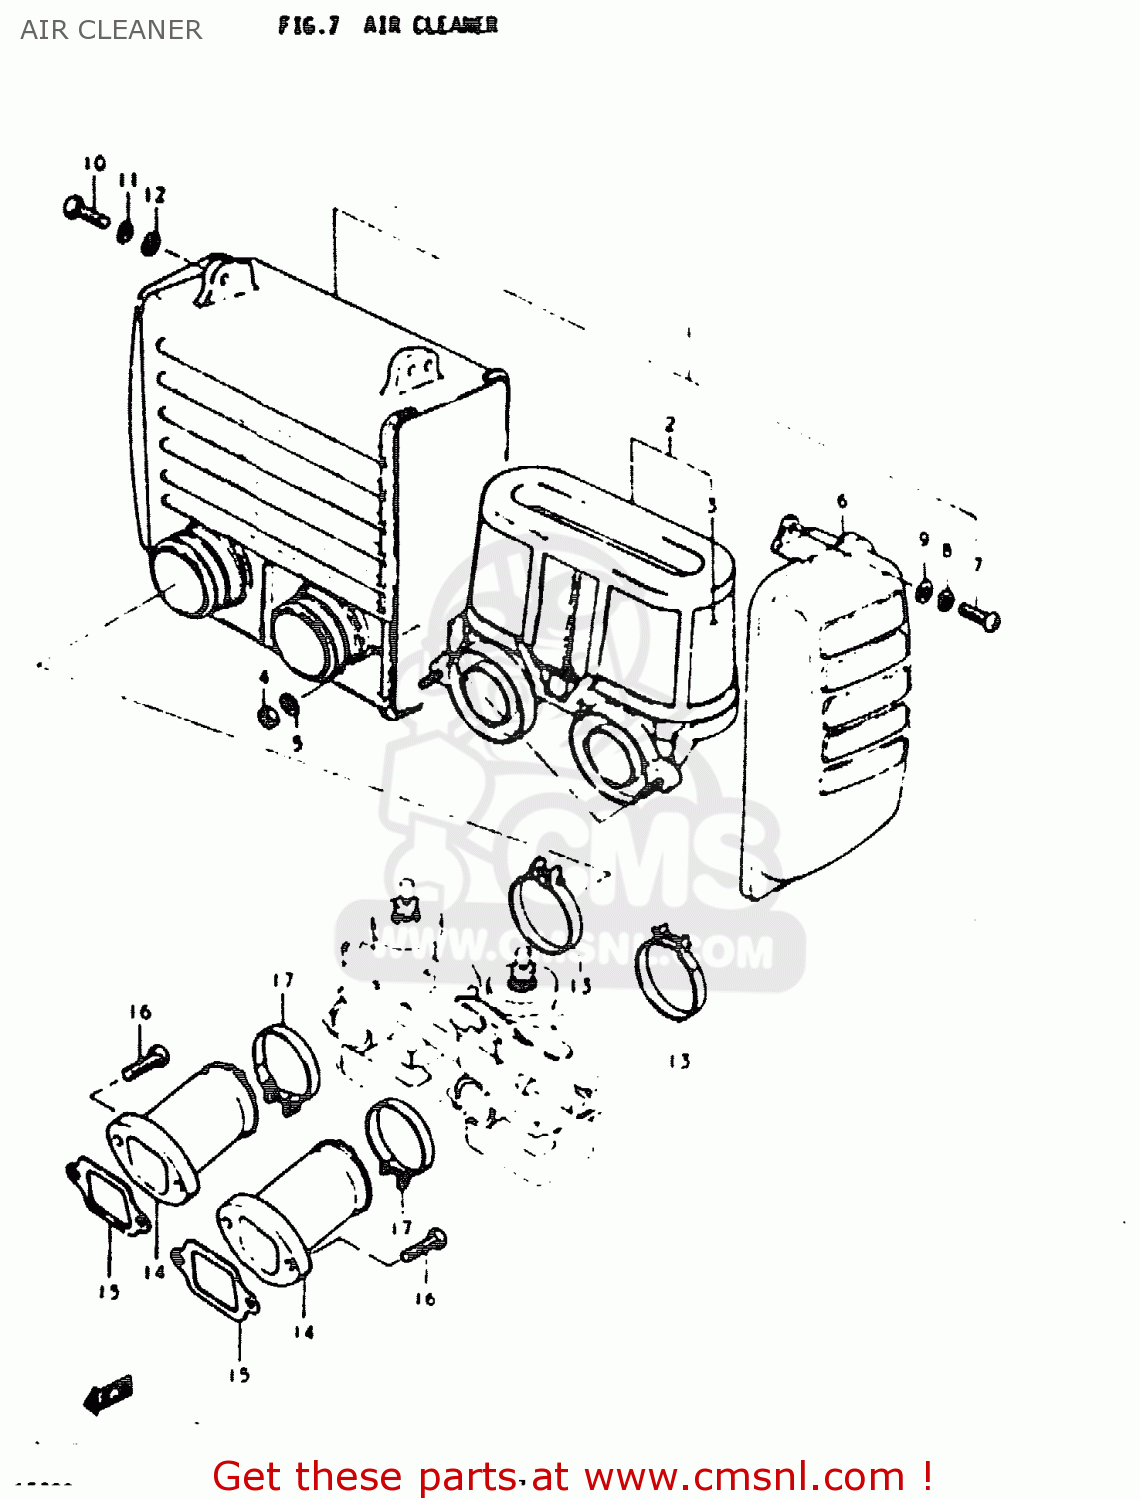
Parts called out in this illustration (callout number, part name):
1	CLEANER ASSY, AIR
2	FILTER ASSY
3	FILTER
4	NUT
5	WASHER
6	CAP
7	SCREW
8	LOCK WASHER
9	WASHER
10	SCREW
11	LOCK WASHER
12	WASHER
13	CLAMP
14	PIPE, INTAKE
15	GASKET,INTAKE PIPE (NAS)
16	SCREW
17	CLAMP
